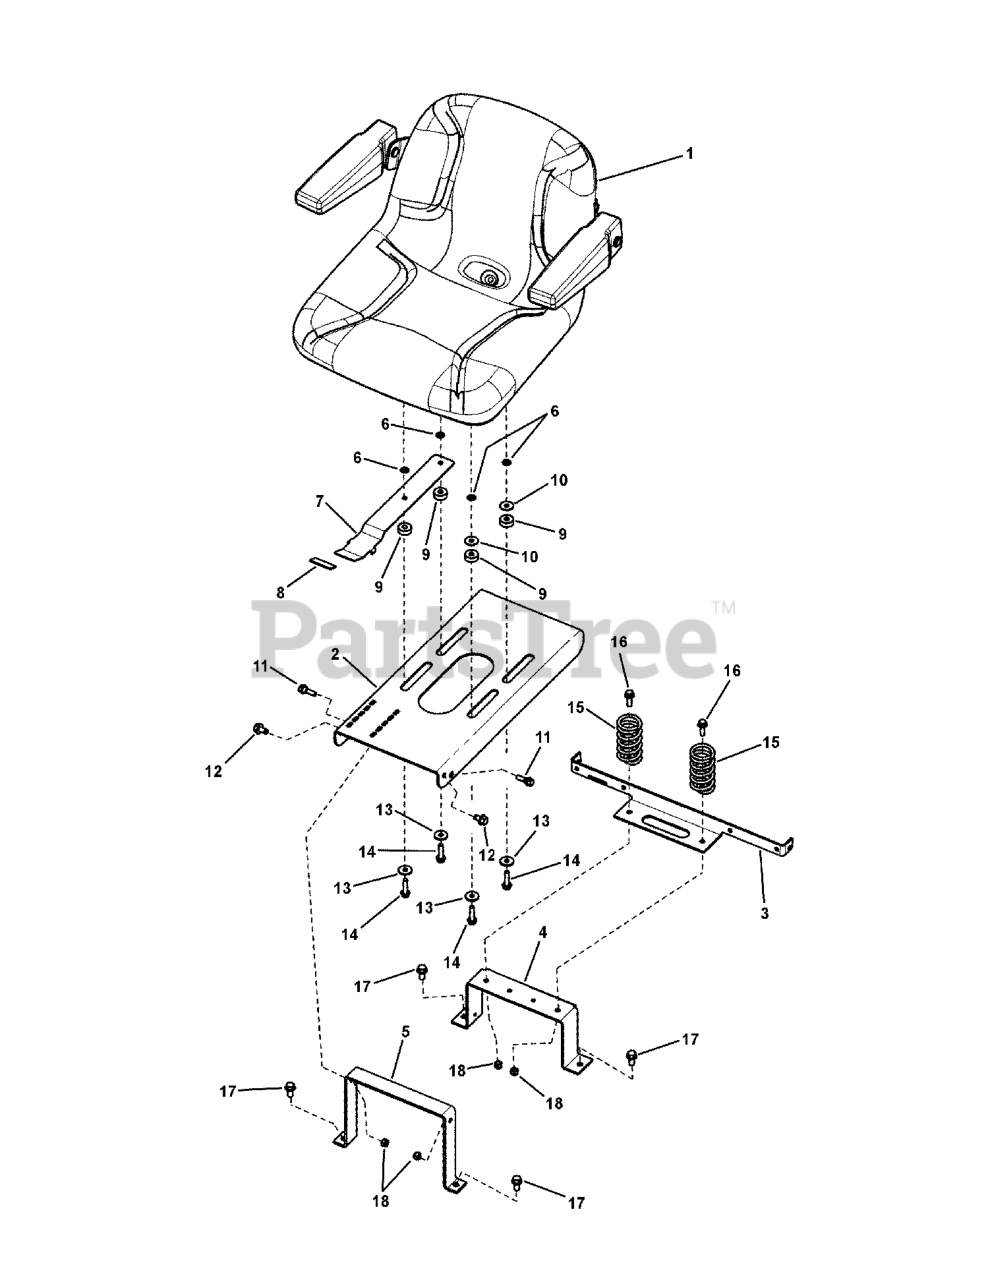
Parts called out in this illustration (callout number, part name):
1	SEAT, 15" Back w/Armrests
2	PLATE, Seat, Adjustable
3	BRACKET, Support, Seat & Fender
4	BRACKET, Seat Support
5	BRACKET, Seat
6	RETAINER, 5/16" Bolt, Black
7	LATCH, Seat
8	COVER, Seat Adjustment Lever
9	SPACER, Seat, Adjustable
10	WASHER, Fender, 5/16"
11	SHOULDER BOLT, 5/16-18, YZ
12	SCREW, 3/8-16 x 5/8" Hex Washer Self-Tap
13	WASHER, 5/16
14	SCREW, 5/16-18 x 1-1/4" Hex Head Flange Lock
15	SPRING, Compression 3.62"
16	BOLT, 5/16-18 x 1" Hex Flange Lock, GR 5, YZ
17	SCREW, 3/8-16 x 3/4" Hex Washer Self-Tap
18	NUT, 5/16-18 Hex Center Lock, GR 5, YZ
